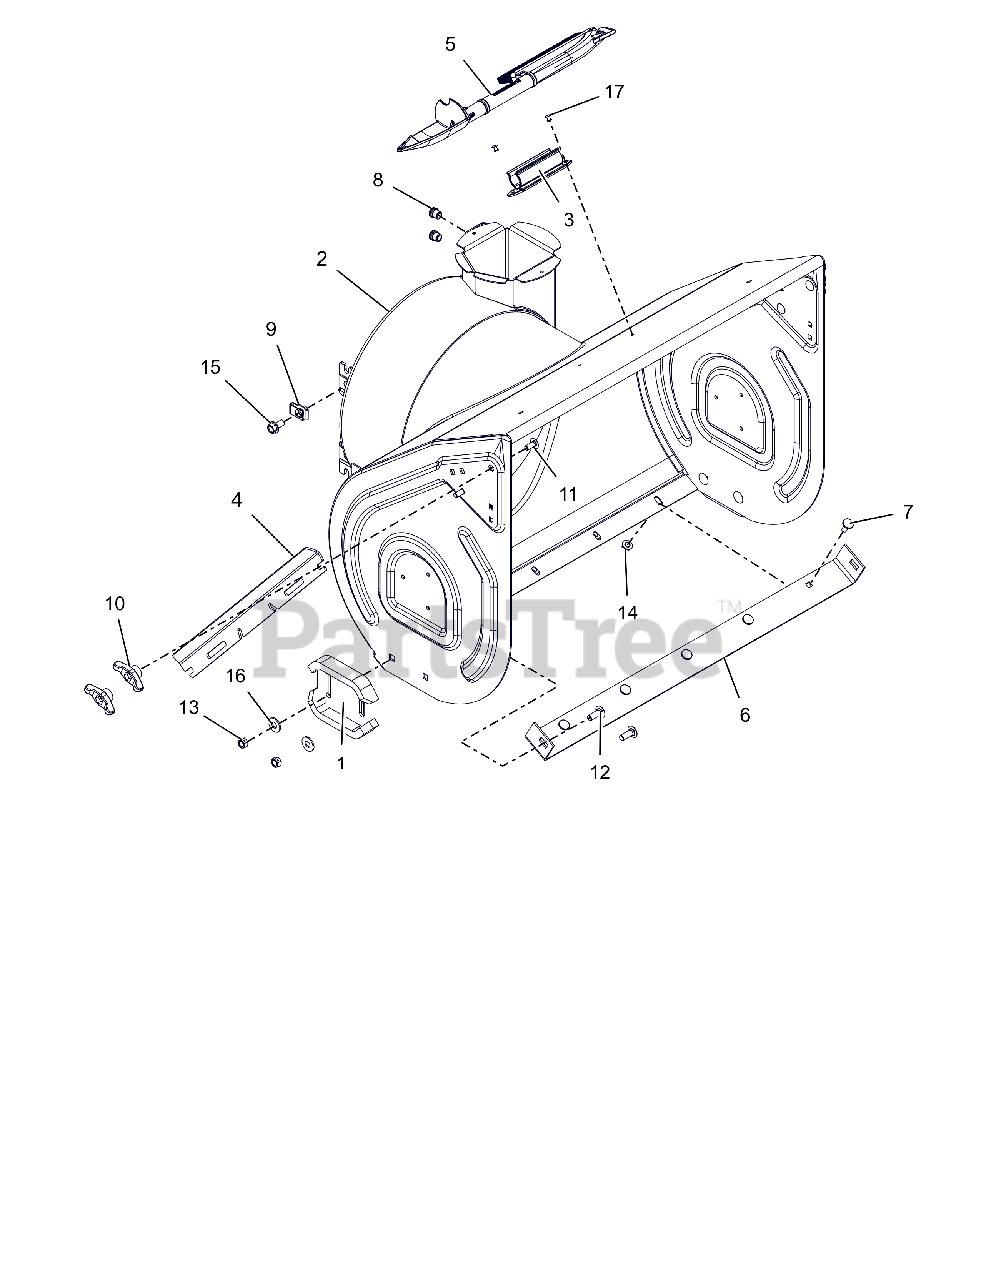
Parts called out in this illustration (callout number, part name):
1	RUNNER, SKID SHOE
2	BLOWER HOUSING W/DECAL 28"
3	MOUNT, SNOW CLEAN OUT
4	CUTTER, DRIFT
5	DEVICE, SNOW CLEAN OUT W/BRUSH
6	BLADE, SCRAPER-28"
7	BOLT, MODIFIED HEAD CARRIAGE
8	NUT, THREADED INSERT .38-16
9	NUT-RTNR .375-16X.37
10	KNOB,WING .31-18 UNC NYL/TALC
11	@BLT-RHDSSQNK .31-18X.75 G5YZ
12	@BLT-RDHDSHSQNK.38-16X1.0 G5YZ
13	@NUT-LK-CTR .38-16 YWZC
14	@NUT-LK-TOP-FLG .31-18 YWZC
15	BLT-SERHFWH .38-16X.75 YWZC
16	@WSHR-FL-STL.438X1.00X.083 YWZ
17	RVT-POP .187 YZ
